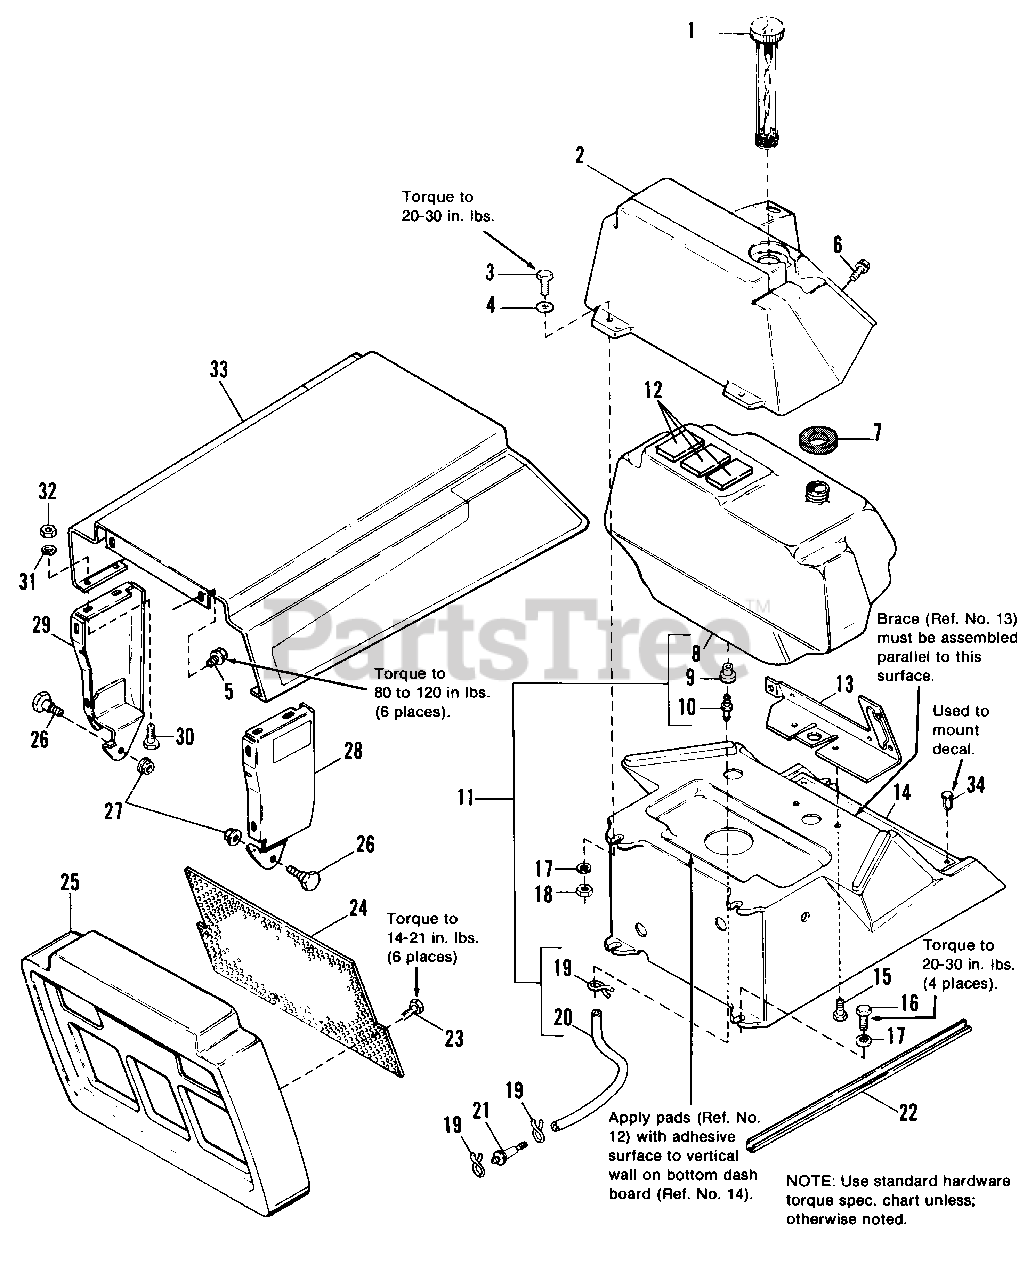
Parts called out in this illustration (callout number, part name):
1	CAP, Fuel Tank
2	DASHBOARD, Top
3	CAPSCREW, Hex, 1/4-20 x 1-1/4
4	WASHER, 1/4
5	SCREW, Plastite, 1/4 x 1
6	SCREW, Hex Washer Hd., 1/4-20 x 5/8
7	WASHER, Foam
11	TANK ASSY., Fuel (Incl. Ref. Nos. 8, 9, 10, 19 (Qty. 1) & 20)
14	DASHBOARD, Bottom
15	SCREW, Taptite, 1/4-20 x 3/4
16	SCREW, Taptite, 1/4-20 x 1
17	LOCKWASHER, Dish, 1/4
18	LOCKNUT, Hex, 1/4-20
19	CLAMP, Hose
21	FILTER, Fuel
22	EDGING, Lower Dash
23	SCREW, Plastite, #10-24 x 1/2
26	BOLT, Shoulder, 5/16-18 x 7/8
27	NUT, Hex, Flange, Two-Way Lock, 5/16-18
28	PANEL ASSY., L.H.
29	PANEL ASSY., R.H.
30	CAPSCREW, Hex, 1/4-20 x 1/2
31	LOCKWASHER, 1/4
32	NUT, Hex, 1/4-20
34	CLIP, Canoe
